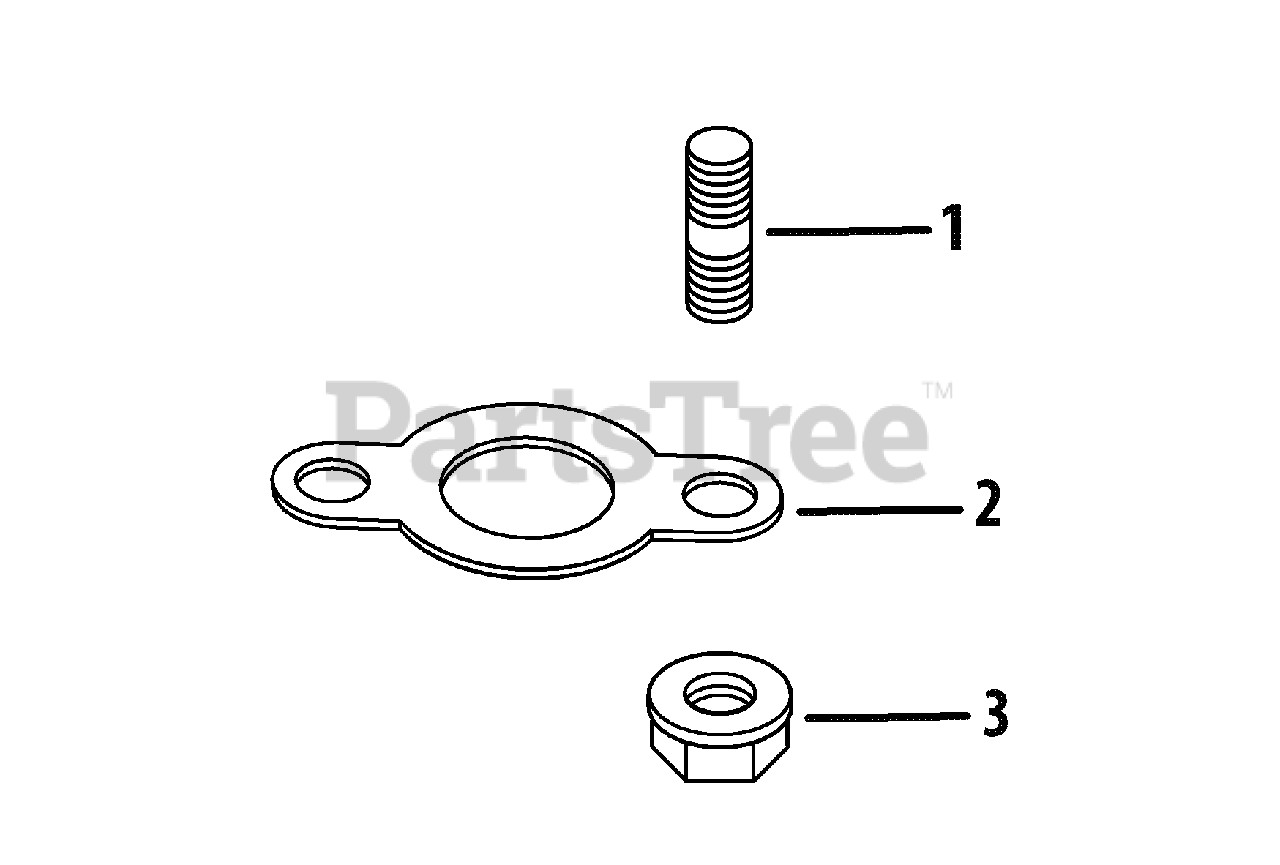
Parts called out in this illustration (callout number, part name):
1	Stud, M8X1.25X33
2	Gasket, Exhaust
3	Nut, Flg M8X1.25
